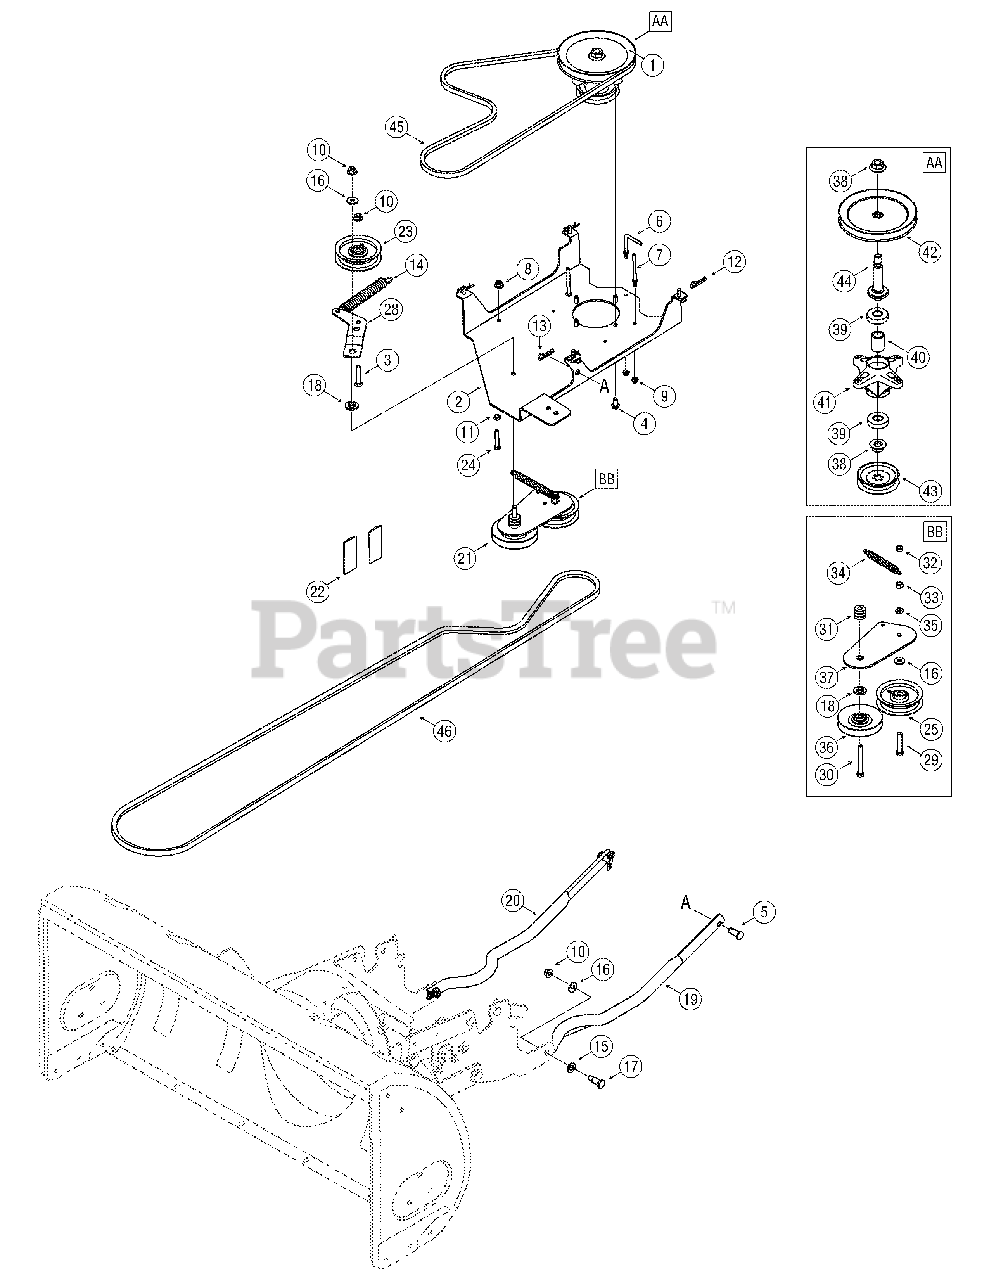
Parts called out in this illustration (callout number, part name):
1	Spindle Assembly (Incl. 38-44)
4	Self Tapping Screw
5	Clevis Pin, .5 x 1.18
6	Belt Keeper Pin
7	Belt Keeper Pin
8	Nylon Hex Lock Nut, 5/16-18
9	Nylon Hex Lock Nut, 1/4-20
10	Hex Flange Lock Nut, 3/8-16
11	Hex Nut, 5/16-18
12	Click Pin, .092 x 1.64
13	Internal Cotter Pin, .125 x 1.75
14	Extension Spring .91 x 7.33
15	Flat Washer, .531 x .93 x .09
16	Flat Washer, .38 x .93 x .11
17	Shoulder Screw, 3/8-16
18	Shoulder Spacer, .625 x .169
21	Double Idler Bracket Assembly
22	Reflector
23	Idler Pulley, 3.50 OD
24	Hex Cap Screw, 5/16-18 x 1.75
25	Idler Pulley 3.50 dia.
26	Idler Assembly Spacer
27	Flange Lock Nut 3/8-16
29	Hex Cap Screw, 3/8-24 x 2
30	Hex Cap Screw, 3/8-16 x 3
32	Nylon Jam Lock Nut, 3/8-24
33	Hex Nut, 3/8-24
34	Extension Spring, .620 x 5.62
35	Lock Washer, 3/8
36	Idler pulley, 4" Diameter
38	Flange Nut 5/8-18
39	Ball Bearing
41	Deck Spindle Housing
42	Deck Pulley 7"
43	Pulley 3.75"
44	Spindle Shaft
45	V-Belt
46	V-Belt
